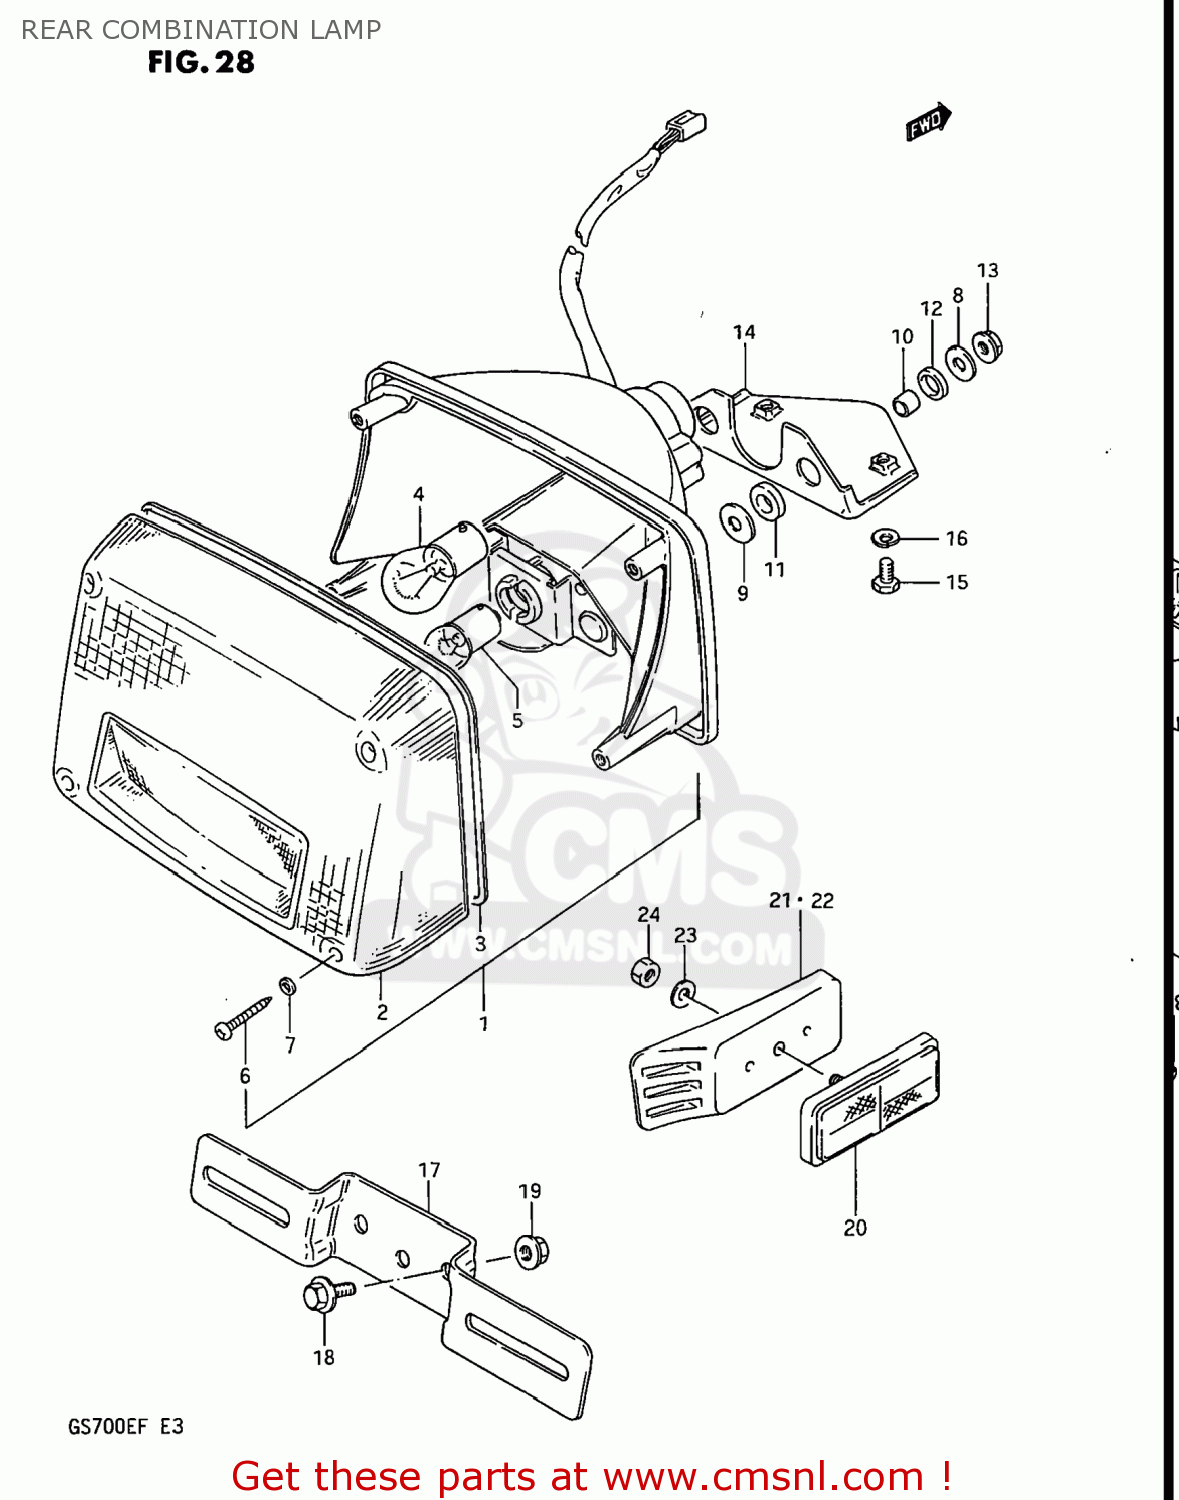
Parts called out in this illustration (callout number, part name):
1	LAMP ASSEMBLY,REAR COMBINATION
2	LENS
3	GASKET (NAS)
4	BULB(12V23W)
5	BULB
6	SCREW,REAR COMBINATION LAMP
7	GASKET (NAS)
8	WASHER
9	WASHER(6,5X22X1.6)
10	SPACER(6.1X9X7.5)
11	CUSHION
12	CUSHION
13	NUT
14	BRACKET,REAR COMBINATION LAMP
15	BOLT
16	WASHER,LOCK
17	PLATE,REAR LICENSE
18	BOLT
19	NUT
20	REFLECTOR,REFLEX
21	SPACER,REAR SIDE REFLECTOR
22	SPACER,REAR SIDE REFLECTOR
23	WASHER(5.2X16X1)
24	NUT
